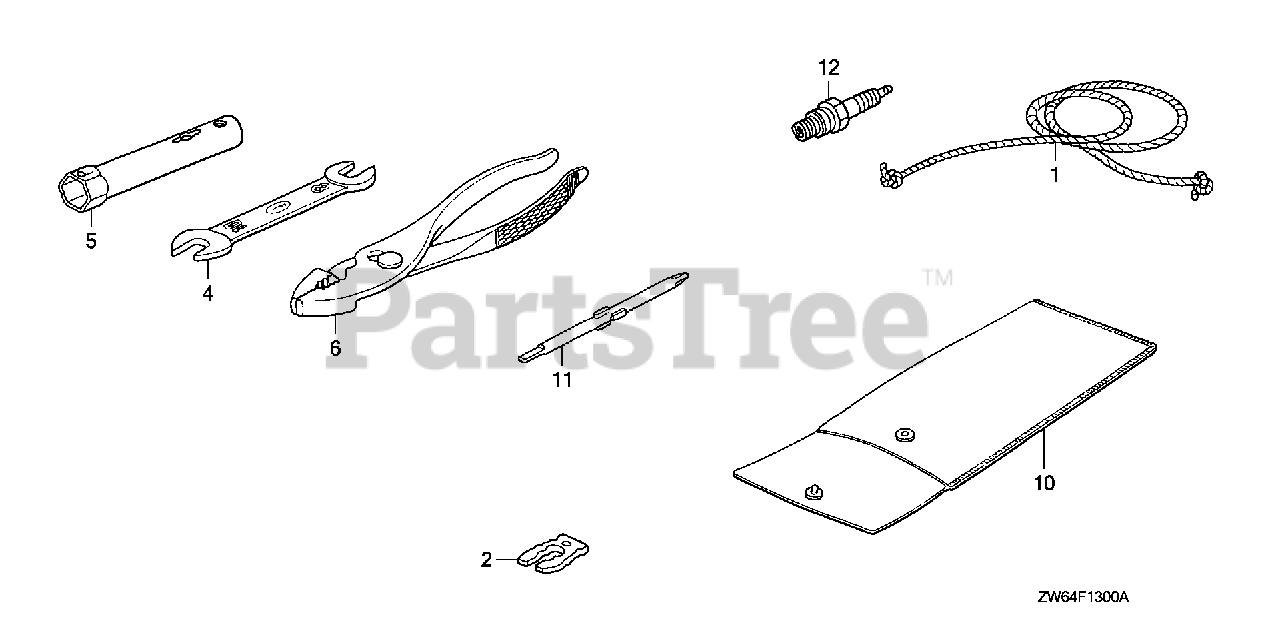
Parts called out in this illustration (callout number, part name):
1	ROPE, STARTER (N/A: USE ALTERNATE P/N 08540-ZG921-11)
2	CLIP, EMERGENCY LOCK
4	SPANNER (8X10)
5	WRENCH, SPARK PLUG
6	PLIERS (135) (KOWA)
6	PLIERS (135)
10	BAG, TOOL (160MM)
12	SPARK PLUG (1UF14-UB)
